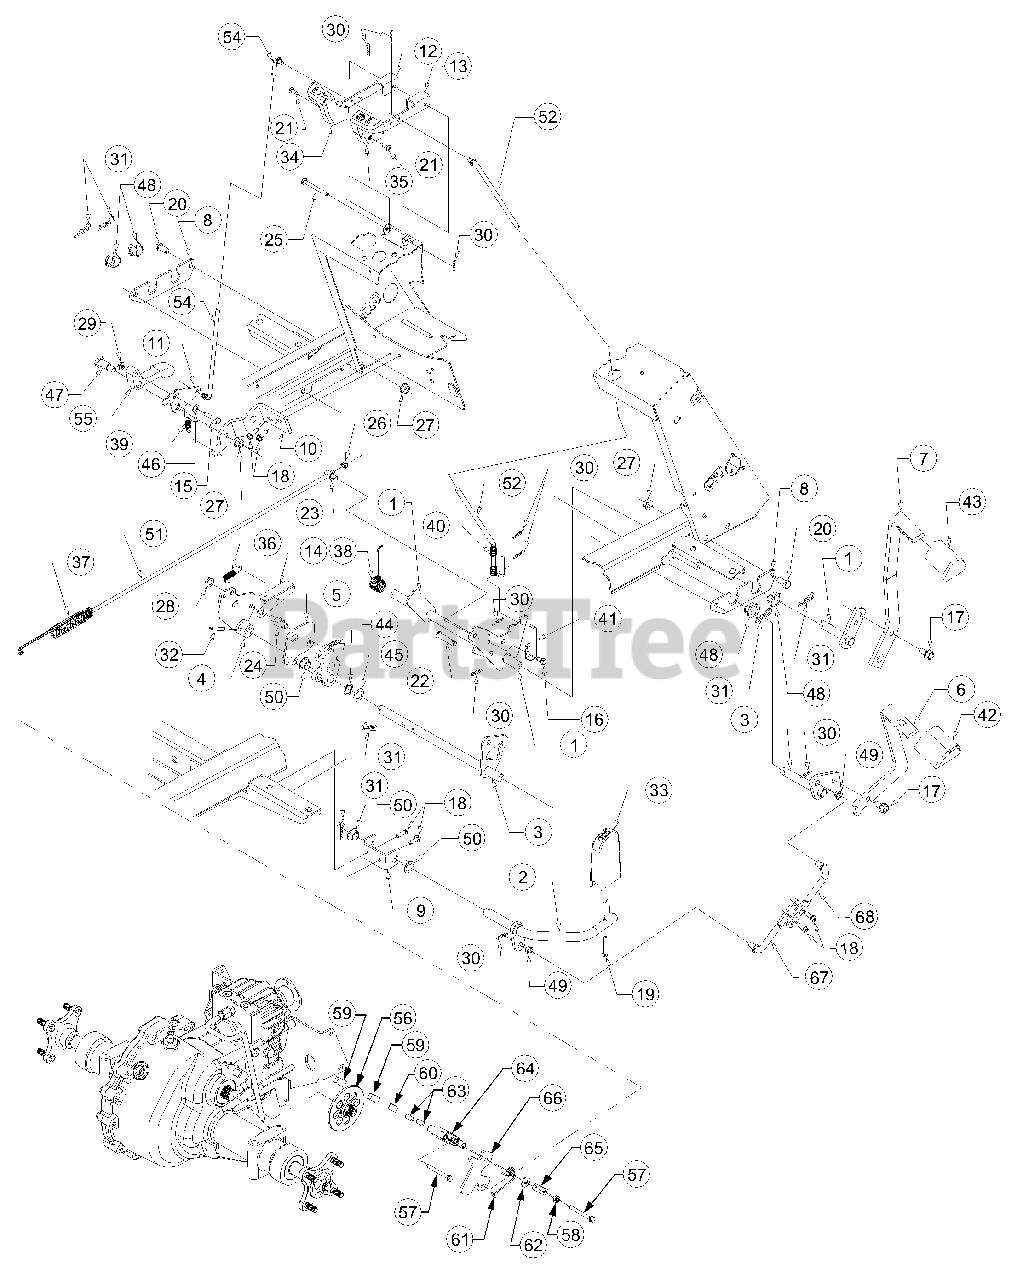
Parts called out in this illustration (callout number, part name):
1	Shaft Assy, Brake
4	Cam Assy, Control
5	Plate Assy, Disengagement
6	Pedal, Forward
8	Plate, Bearing Mounting
10	Bracket, Cruise
11	Plate, Rod Adjustment
15	Screw, Hex Cap, 1/4-20 x 1.25
16	Screw, Hex Wash Hd Tapp 1/4-20 x .5
17	Screw, Hex Wash Hd Tapp 3/8-16 x .75
18	Screw, Hex Wash Hd Tapp 1/4-20 x .75
19	Screw, Truss Mach, #12 x 1.5
20	Screw, Hex Cap, 3/8-16 x .75 GR5
21	Screw, Phil Hd Pan, #10-24 x .75
22	Pin, Clevis, 3/8 x 1.62
23	Ferrule, Adjustment, 1/4-20 Thrd
24	Stud, Actuator
25	Pin, Clevis, .25 x 2.38
26	Nut, Hex Sems, 1/4-20
27	Nut, Hex Flange Lock, 3/8-16
28	Nut, Hex Flange Lock, 5/16-18
29	Nut, Hex Flange Lock, 1/4-20
30	Pin, Internal Cotter, 5/16 Dia x 1.12
31	Pin, Internal Cotter, 3/8 Dia x 1.62
32	Pin, Spiral Spring, 1/4 x 1.5
33	Pedal, Reverse
34	Knob, Cruise
35	Knob, Brake Lock
36	Spring, Extension, .38 OD x 2.1
37	Spring, Extension
38	Spring, Torsion
39	Spring, Extension, .6 OD x 1.34
40	Spring, Compression, .50 x 2.23
41	Spring, Switch Actuator
42	Pad, Forward Foot Control
43	Pad, Brake Foot
44	Washer, Wave, .625 x .885 x .015
45	Washer, Flat, .635 x 1.0 x .020
46	Washer, Flat, 1/4 x .63 x .051
47	Shoulder Bolt, .50 OD x .840
48	Bearing, Hex Flange Split
49	Bearing, Flange, .375 x .58 x .25
50	Bearing, Flange, .626 x .93 x .344
51	Rod, Brake
52	Rod, Parking Brake
54	Rod, Cruise
55	Latch, Cruise
56	Disc, Brake
57	Screw, Hex Wash Hd, Tapp, 1/4-20 x 2.375
58	Nut, Hex Nylon Lock, 5/16-24
59	Pad, Brake
60	Plate, Puck
61	Spring, Torsion
62	Washer, Flat, .343 x .88 x .062
63	Pin, Brake Actuating
64	Yoke, Brake
65	Bracket, Brake Anti Rotation
66	Arm, Brake Actuator
67	Rod, Rear Connecting
68	Rod, Front Connecting
